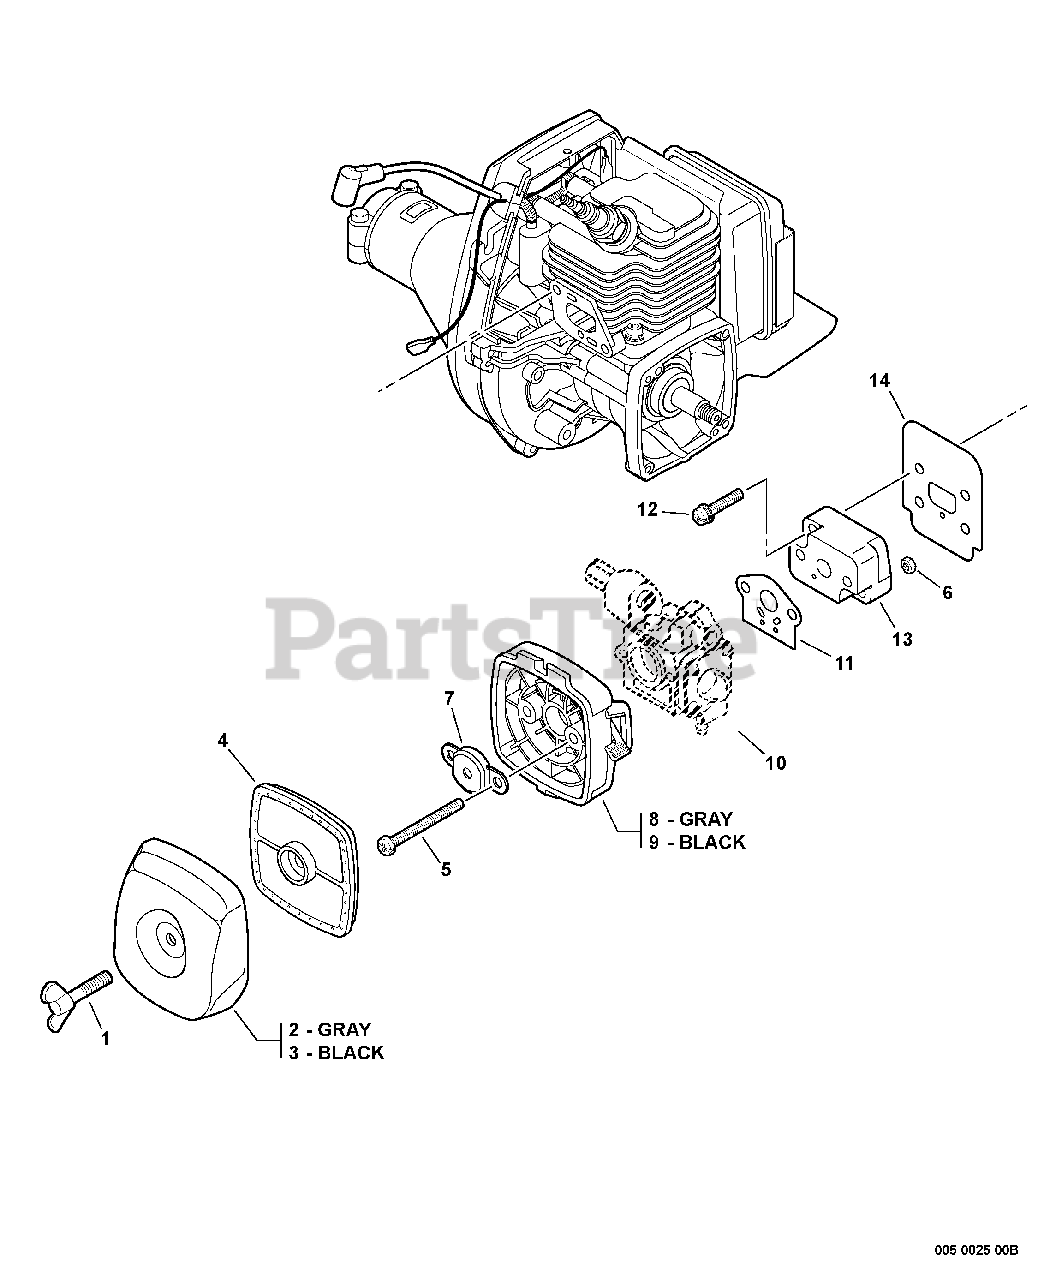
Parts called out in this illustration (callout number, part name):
1	BOLT, WING 5×20
2	COVER, AIR FILTER - GRAY
3	COVER, AIR FILTER - BLACK
4	FILTER, AIR - SINGLE LAYER
5	SCREW 5×65
6	NUT M5
7	PLATE, PREVENT
8	CASE, AIR FILTER - GRAY
9	CASE, AIR FILTER - BLACK
10	CARBURETOR
11	GASKET, CARBURETOR
12	SCREW 5×20
13	INSULATOR, INTAKE
14	HEAT SHIELD, INTAKE
